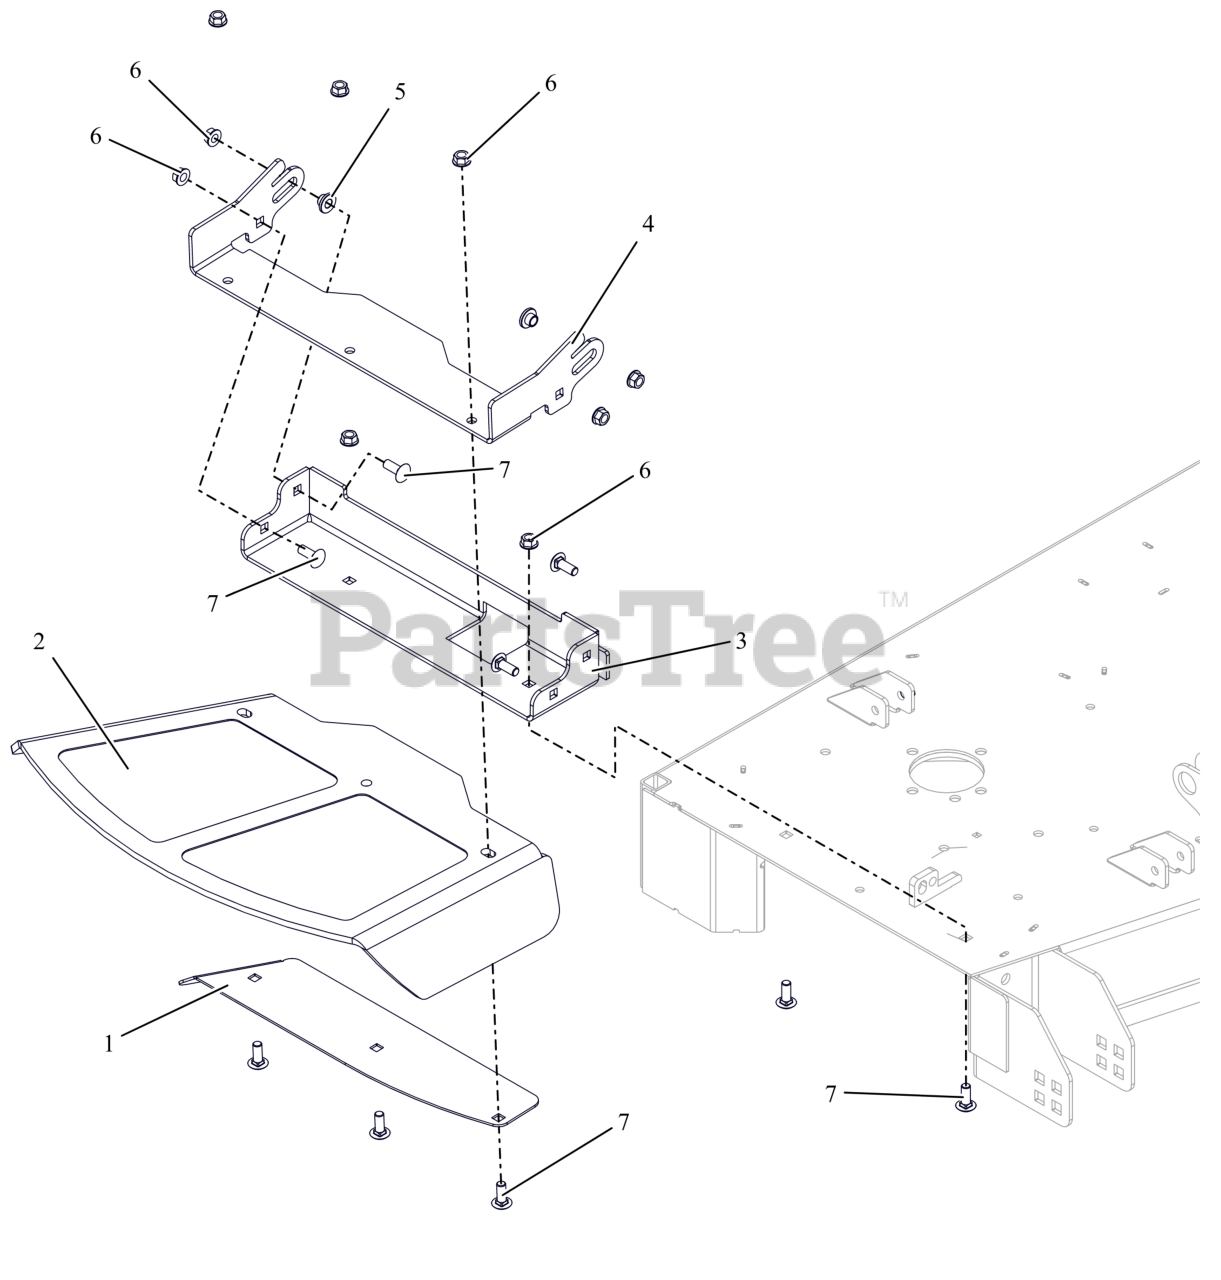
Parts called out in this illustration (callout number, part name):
1	48-60 DISCH CHUTE CLMP PLT-ORG
2	CHUTE, FORMED RUBBER DISCHARGE
3	KIT-DISCH CHUTE SM ORG W/DECAL
4	BRKT- CHUTE MTG
5	BSHG-FLG .385X.500X.875X.406
6	NUT-LK-CTR-FLG .375-16 GF ZCC
7	BLT,RHSSN .38-16X1.00 G5 ZCC
